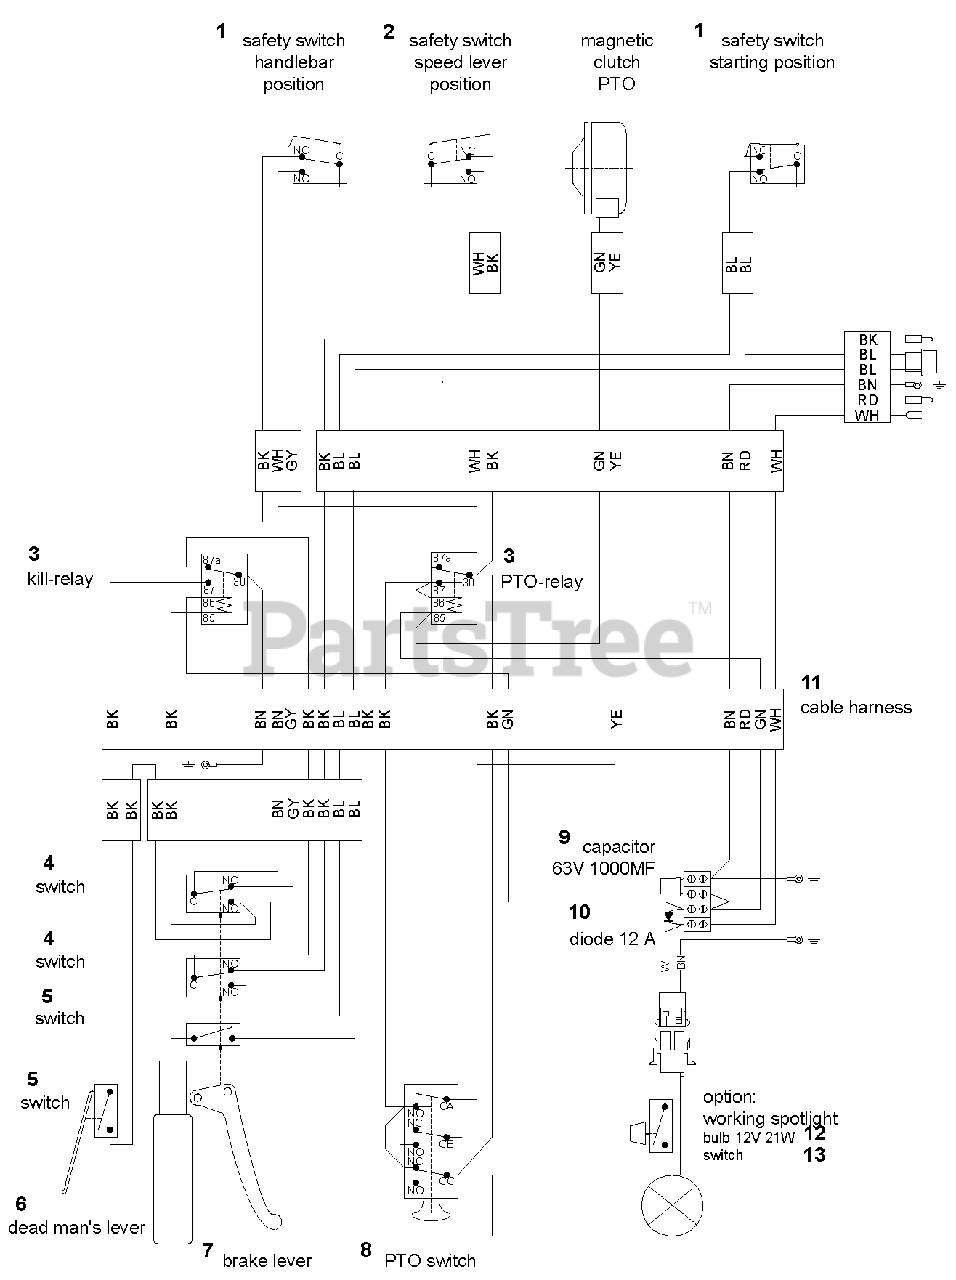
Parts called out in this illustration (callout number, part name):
2	Driving, Switch
4	Switch, Micro
6	Lever, Emergency
7	Lever, Control
8	Switch, PTO
9	Condensator
11	Cable Harness
12	Bulb, 12V 21W
